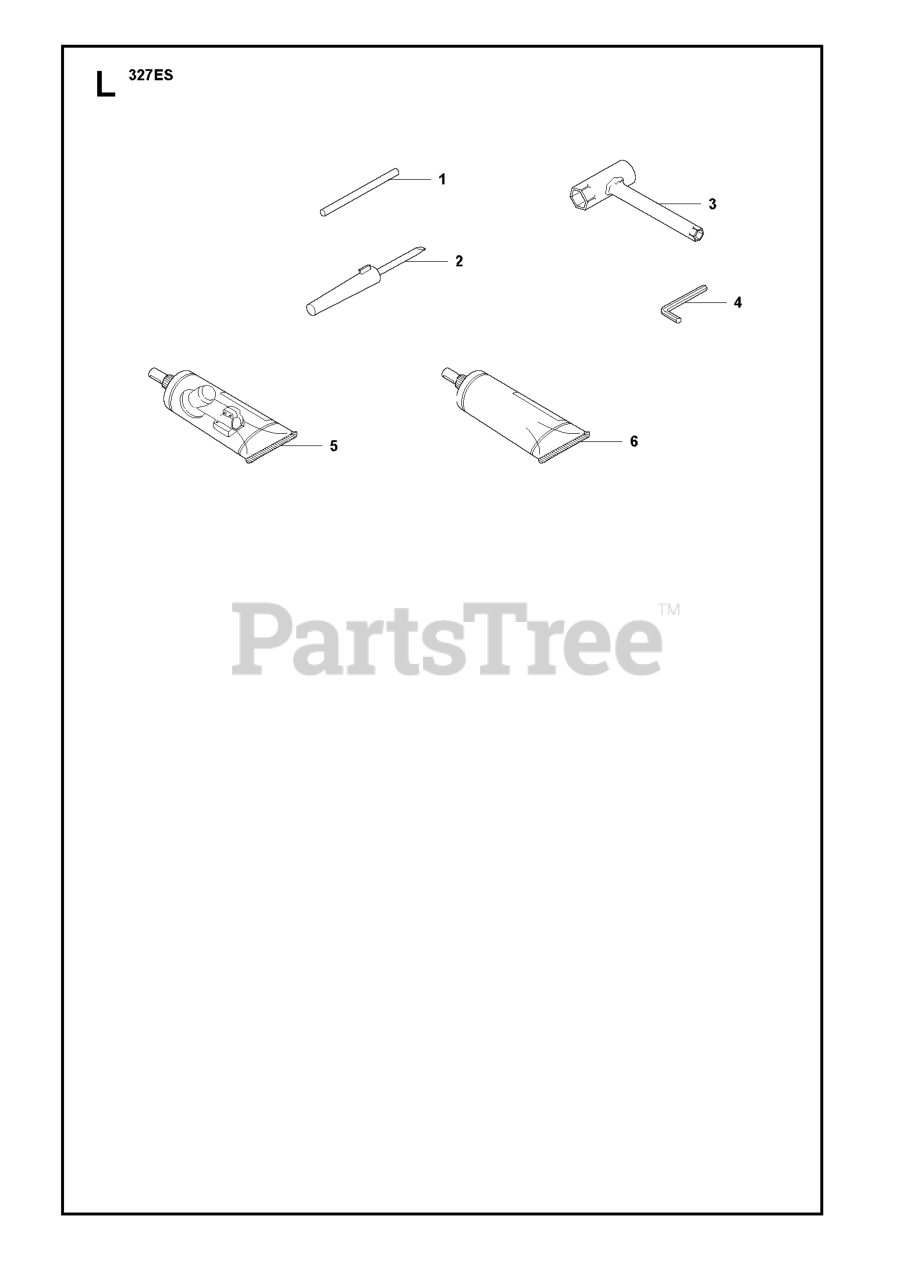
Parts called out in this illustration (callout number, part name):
1	LOCKING PIN
2	SCREWDRIVER
3	COMBI WRENCH
4	L-KEY WRENCH
5	BEVEL GEAR GREASE
6	DRIVE SHAFT GREASE (200 G)
